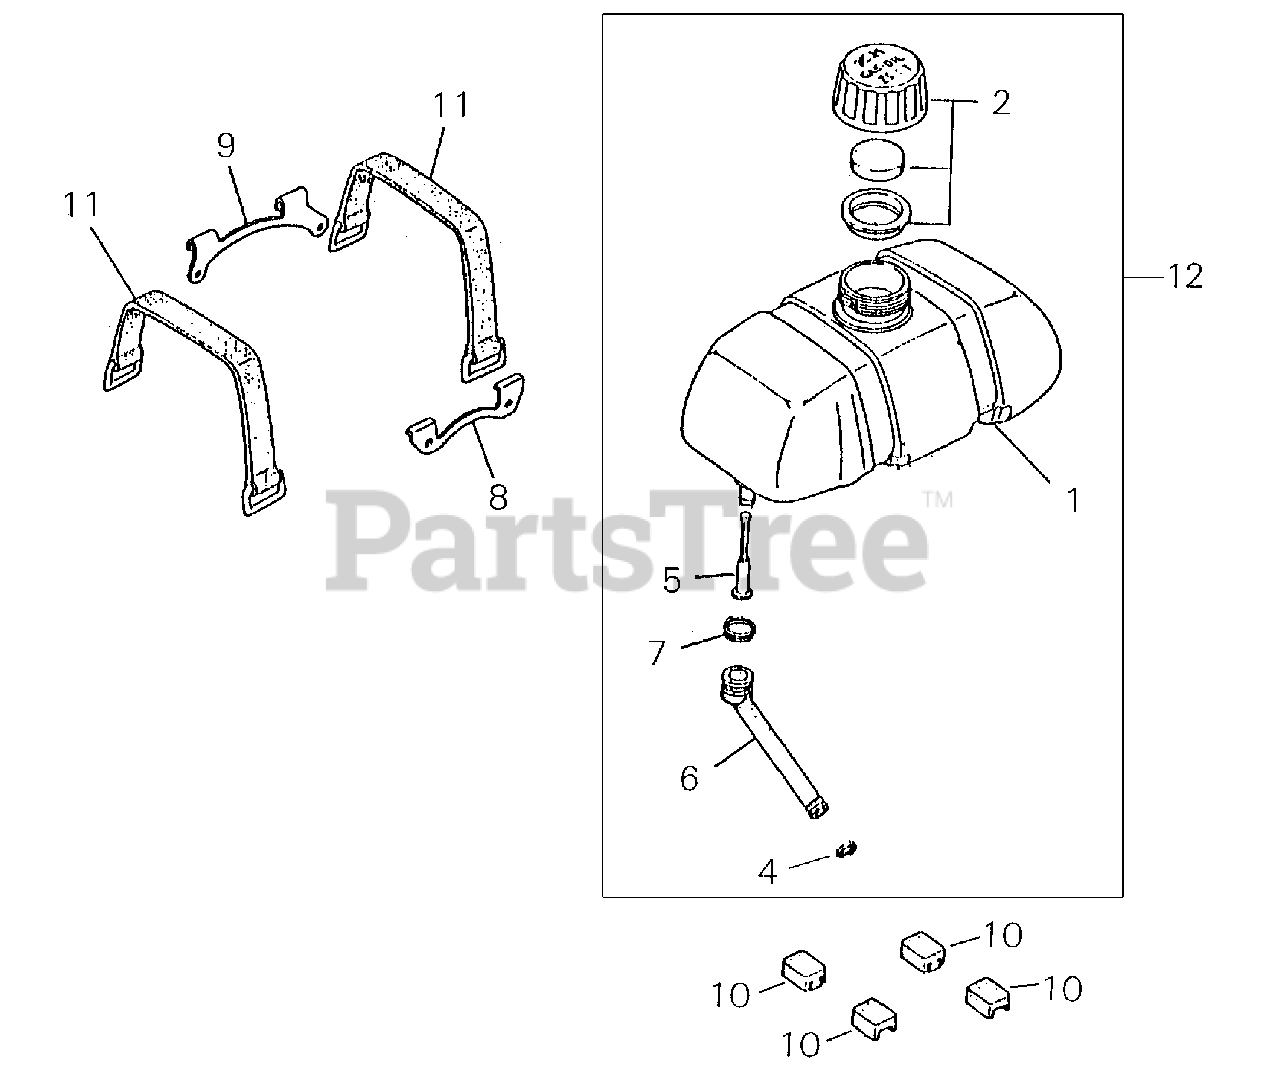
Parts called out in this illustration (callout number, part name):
1	TANK, FUEL
2	CAP ASSY, FUEL
4	CLIP
5	FILTER, FUEL
6	PIPE, FUEL
7	CLIP
8	BRACKET S
9	BRACKET M
10	CUSHION, FUEL TANK
11	STRAP, FUEL TANK
12	TANK ASSY, FUEL
